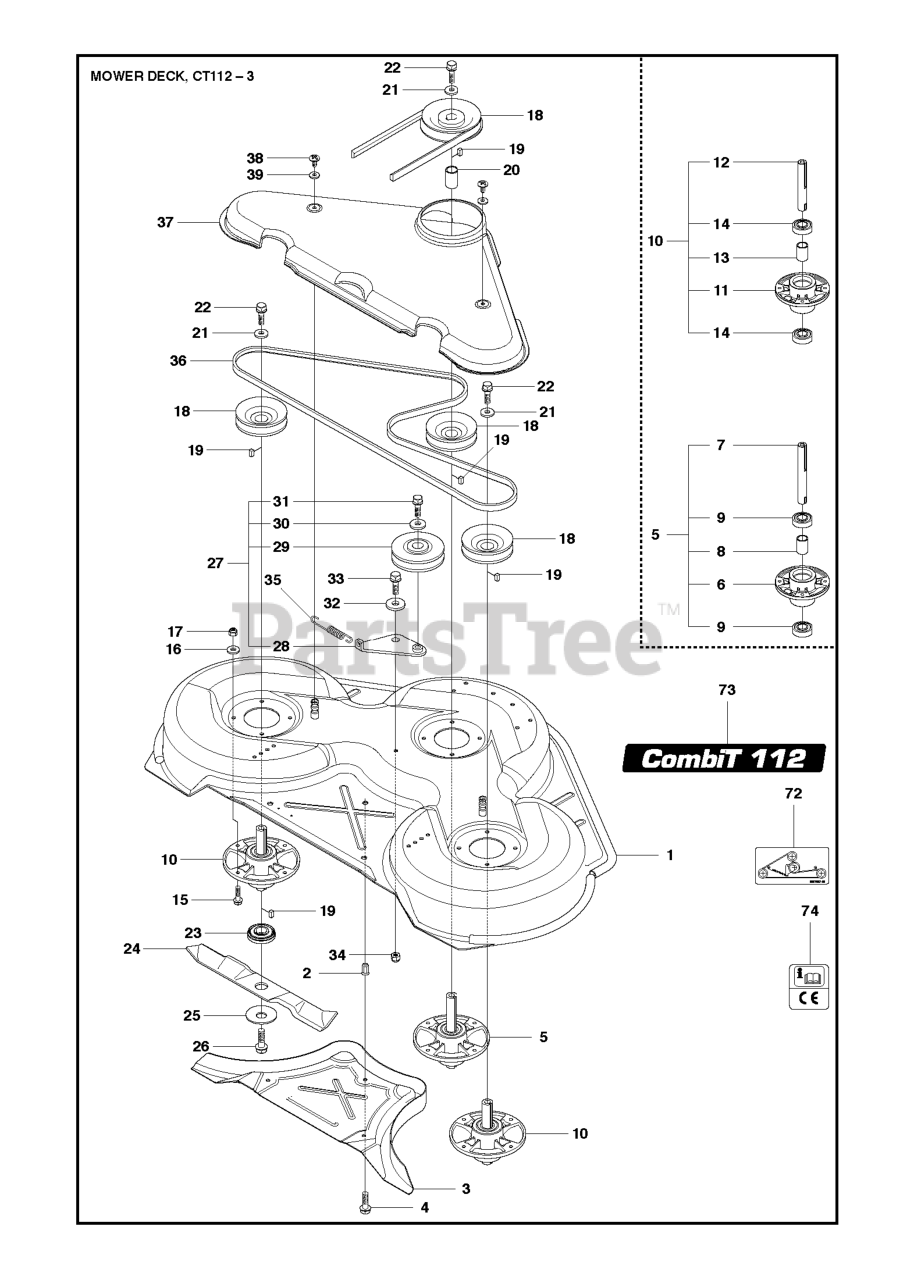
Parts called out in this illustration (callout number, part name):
6	BEARING HOUSING
9	BALL BEARING
11	BEARING HOUSING
14	BALL BEARING
16	WASHER BRB 8.4X17
17	LOCKNUT M8
27	BELT TENSIONER ASSY
28	BELT TENSIONING ARM
32	WASHER
34	LOCKNUT M8
36	BELT
37	BELT COVER
